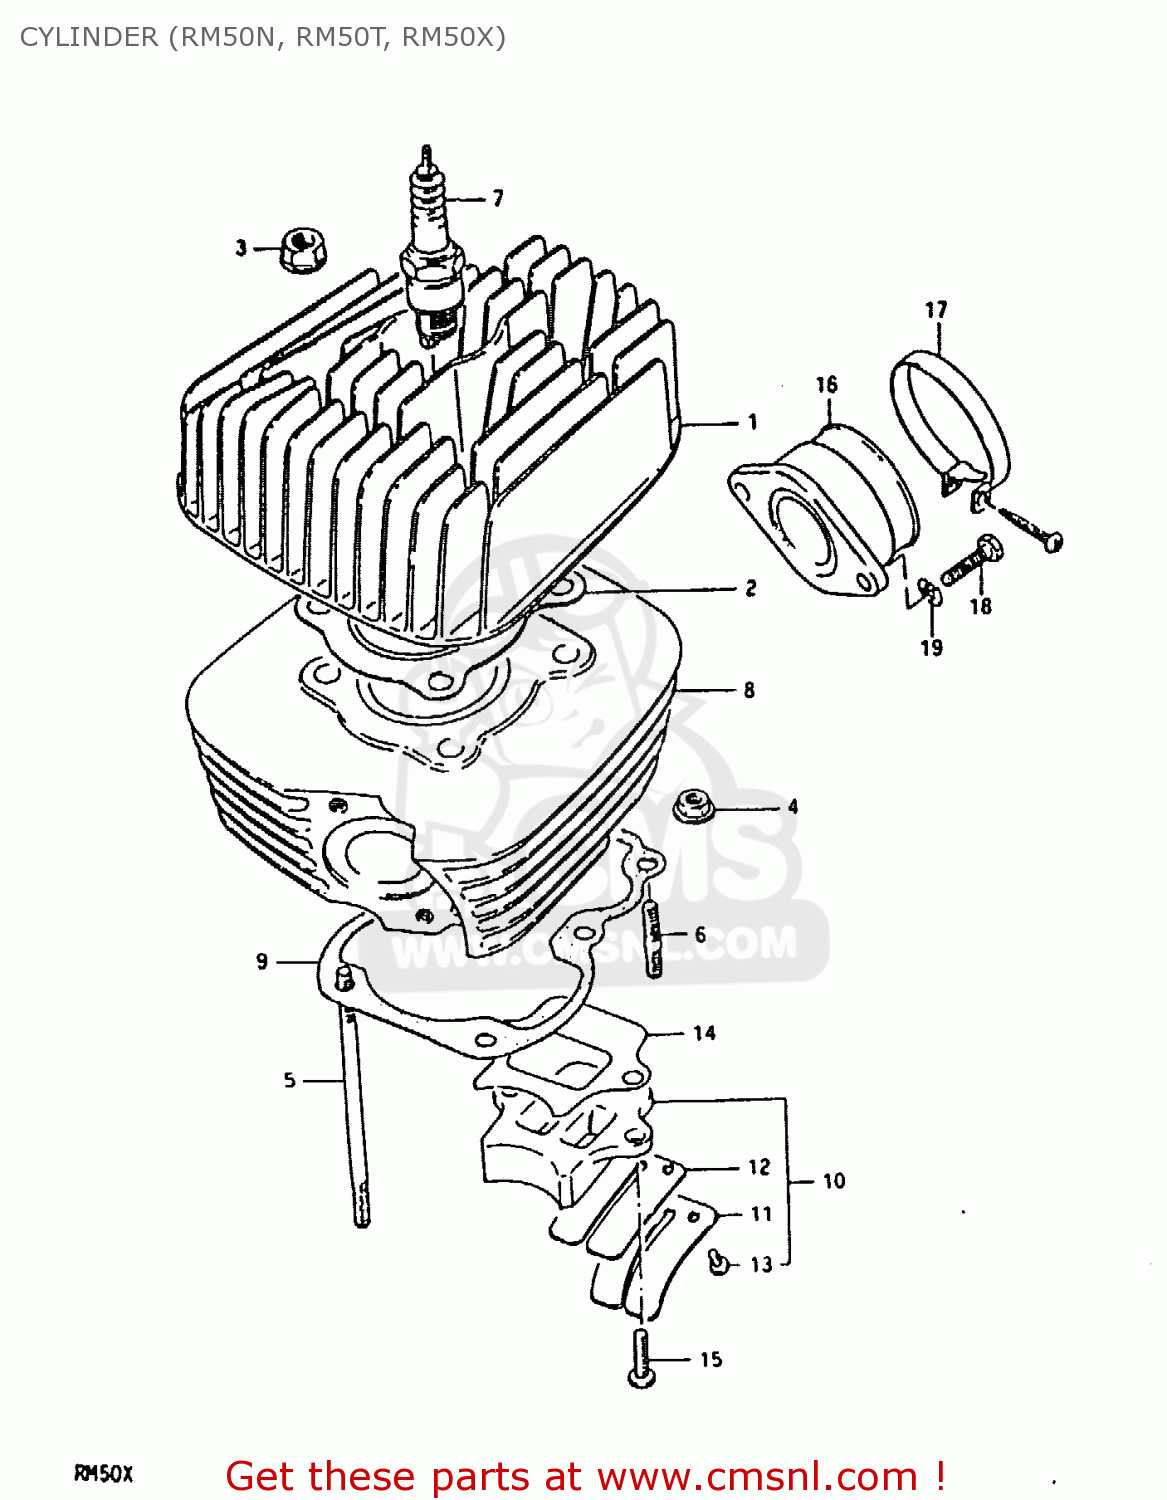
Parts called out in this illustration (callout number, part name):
1	HEAD,CYLINDER
2	GASKET,CYLINDER HEAD (NAS)
3	NUT
4	NUT
5	STUD BOLT
6	STUD BOLT
7	PLUG,SPARK(B7HS)
8	CYLINDER
9	GASKET,CYLINDER
10	VALVE ASSY,REED
11	STOPPER,REED VALVE
12	VALVE,REED
13	SCREW,REED VALVE
14	GASKET,REED VALVE (MCA)
15	SCREW
16	PIPE,INTAKE
17	CLAMP
18	BOLT, UPPER
19	LOCK WASHER
